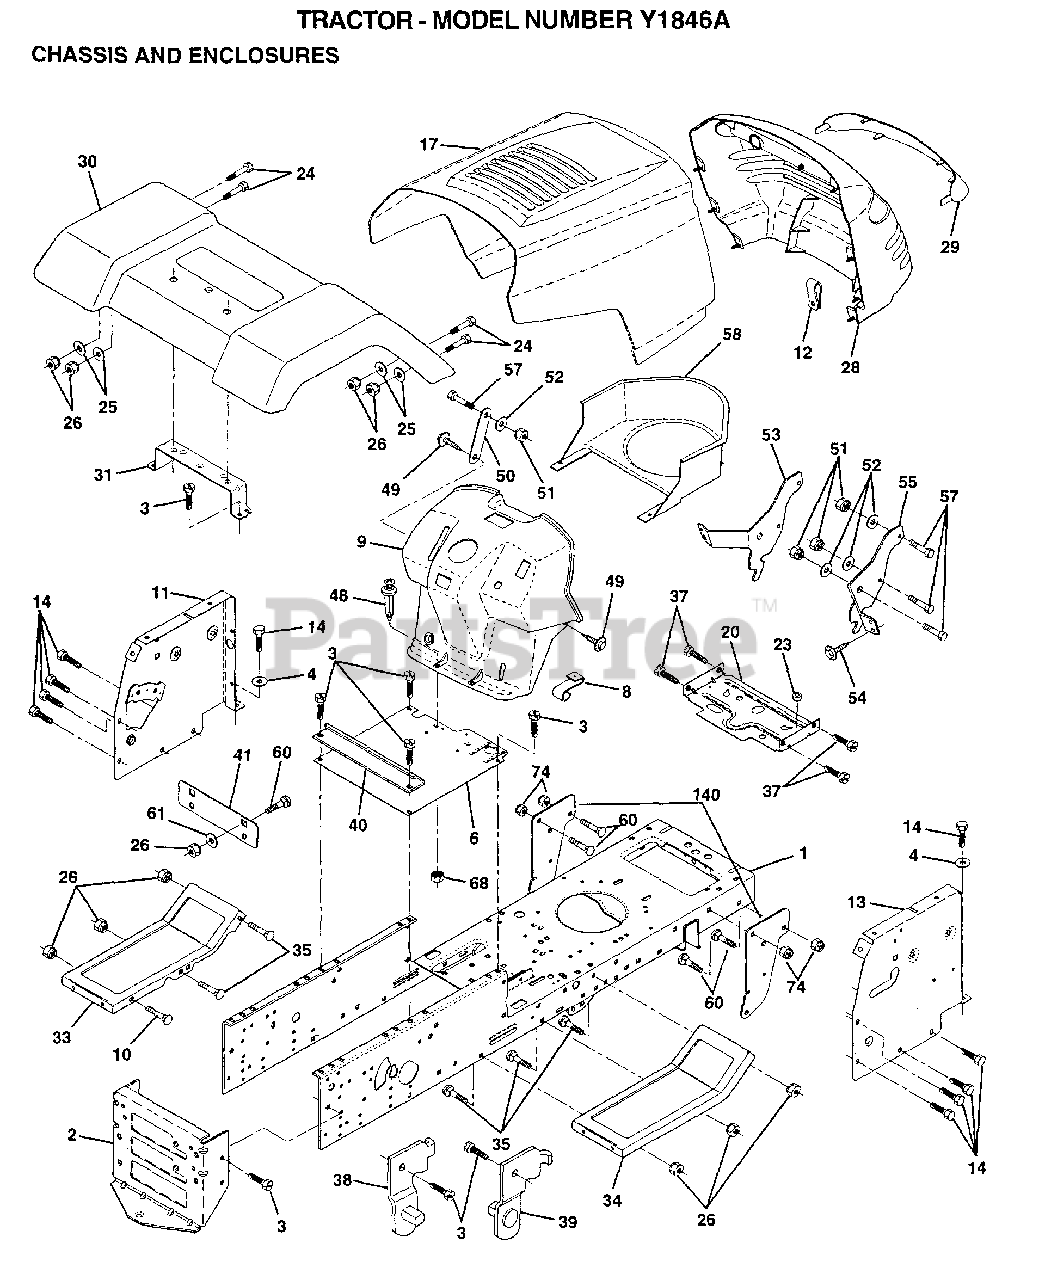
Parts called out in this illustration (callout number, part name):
4	NUT
5	BOLT.SHLD.5/16-18
6	CLIP.PUSH-IN.HING
8	BOLT
9	BRACKET PVT SEAT
10	"CLIP,INSULATOR"
11	WASHER
12	NUT
13	BOLT
14	LOCKWASHER
15	WASHER
16	"BOLT,SHOULDER"
17	BRKT SWITCH
19	BUSHING
20	SPRING
21	SPLIT SPACER
